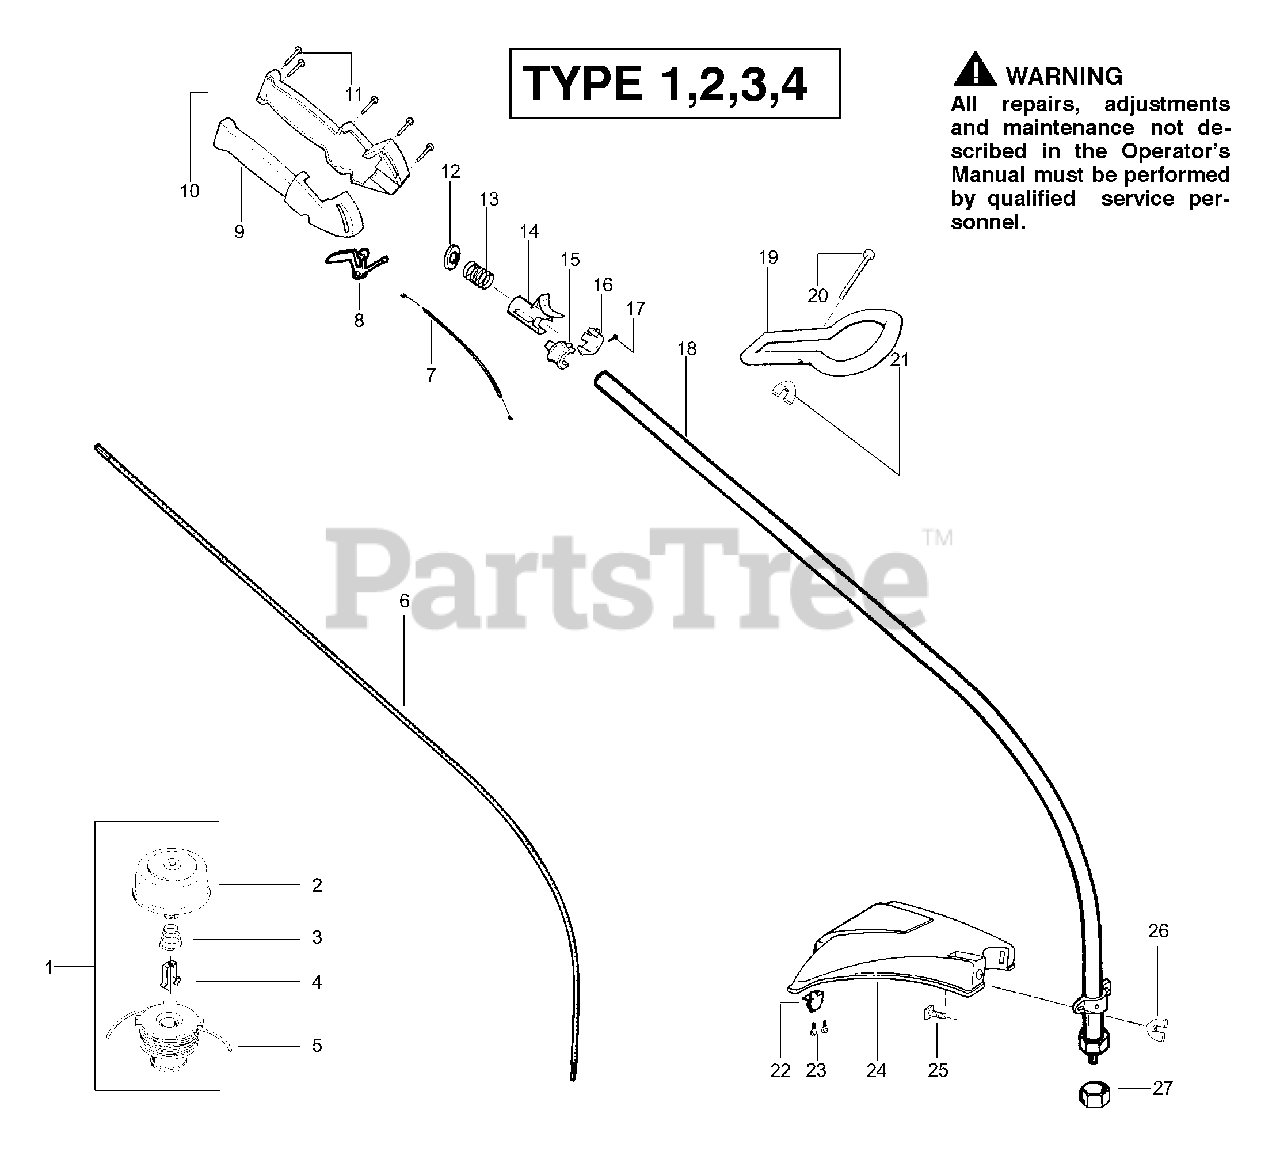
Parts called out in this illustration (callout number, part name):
1	Accy-Cutting Head Ass'y. (type 1,2)
1	Accy-Cutting Head Ass'y. (type 3,4)
2	Assy-Hub (type 1,2)
2	Assy-Hub (type 3,4)
4	Clip-Retainer-Head
5	Spool w/Line
6	Drive Shaft-Flex (type 1,2)
6	Drive Shaft-Flex (type 3,4)
7	Assy-Throttle Cable (type 1,2)
7	Assy-Throttle Cable (type 3,4)
9	Throttle Hsg. (Right)
10	Throttle Hsg. (Left)
11	Screw-Throttle Hsg.
14	Actuator
15	Locator-Right
16	Locator-Left
17	Screw
18	Assy-Drive Shaft Hsg. (type 1,2)
18	Assy-Drive Shaft Hsg. (type 3,4)
19	Assist Handle
20	Bolt-Handle
21	Wingnut
22	Line Limiter
23	Screw-Line Limiter
24	Kit-Shield Ass'y.
25	Bolt-Shield
26	Wingnut
27	Dust Cup (type 1,2)
27	Dust Cup (type 3,4)
